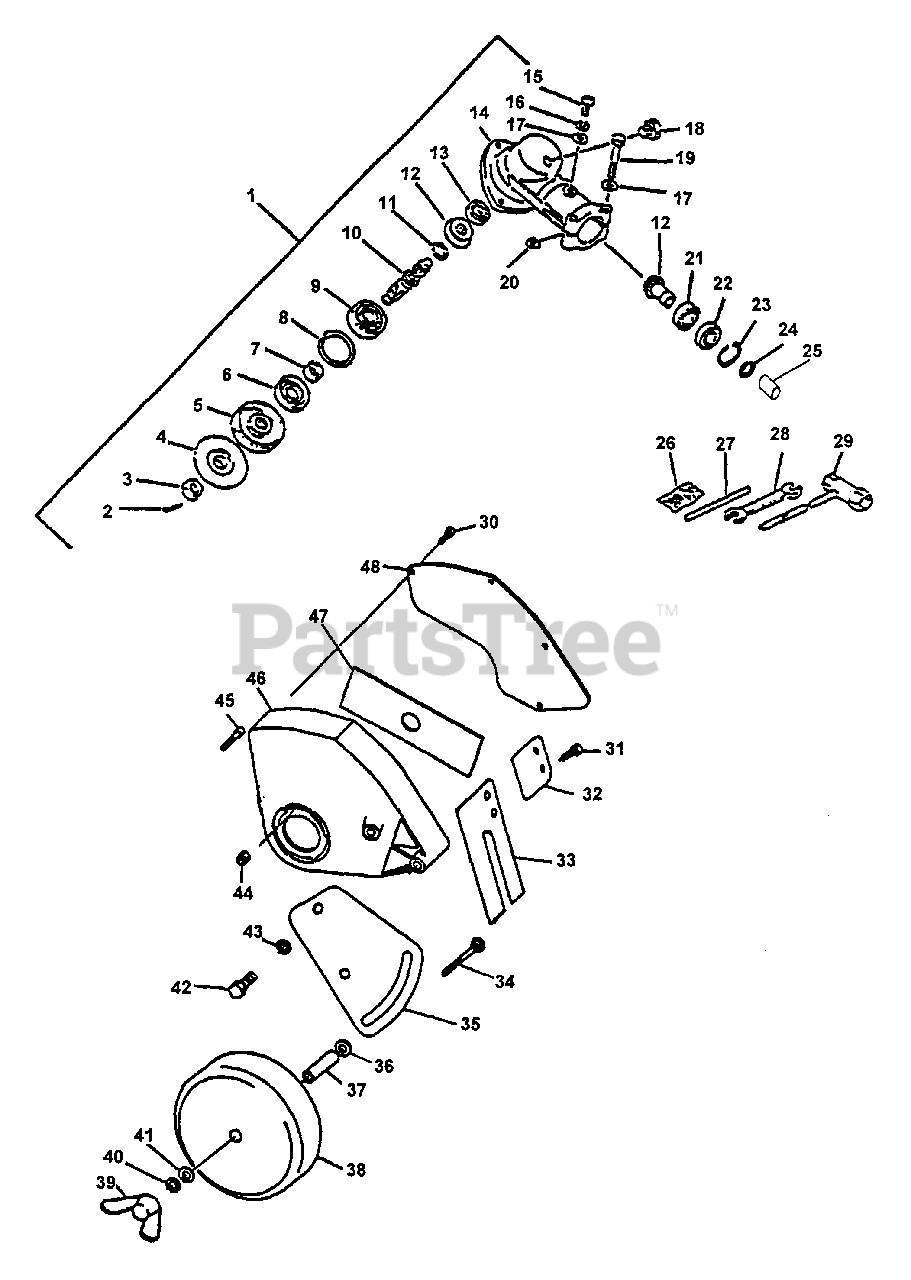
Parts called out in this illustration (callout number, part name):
1	GEAR CASE ASSY
2	PIN, COTTER 2×22
4	PLATE, ADAPTOR - LOWER
5	PLATE, ADAPTER - UPPER
6	SEAL, OIL 22
7	SPACER 11.8×15×9
8	RING, SNAP Ø32
9	BEARING, BALL - 6201 C3
10	SHAFT, GEAR
11	RING, SNAP Ø10
12	GEAR SET
13	BEARING, BALL 609
14	HOUSING, GEAR CASE
15	SCREW 5×10
16	WASHER, SPRING 5
17	WASHER, FLAT 5.5×10×0.8
18	BOLT 8×8 SP
19	BOLT 5×35 SP
21	BEARING, BALL 6900
22	BEARING, BALL 6900Z
23	RING, SNAP Ø22
24	RING, SNAP Ø12
25	COLLAR
26	PIN, COTTER 2×22 (PKG. OF 10)
27	TOOL, LOCKING 5×120 MM
28	SPANNER 8×10
29	T-WRENCH 17x-19 L200
30	BOLT 4×12
31	BOLT 4×14
32	PLATE, FLAP
33	FLAP, DEBRIS
34	BOLT 5/16"-18×2-1/2"
35	BRACKET, WHEEL
36	WASHER, SPRING 10
37	COLLAR 12
38	WHEEL
39	KNOB, FASTENER
40	WASHER, SPRING 8
42	BOLT 8×14
43	WASHER, SPRING 8
44	NUT, LOCK M5
45	BOLT 5×22
46	NEW BLADE SHIELD
47	BLADE - 2 PK
48	SHIELD, DEBRIS
